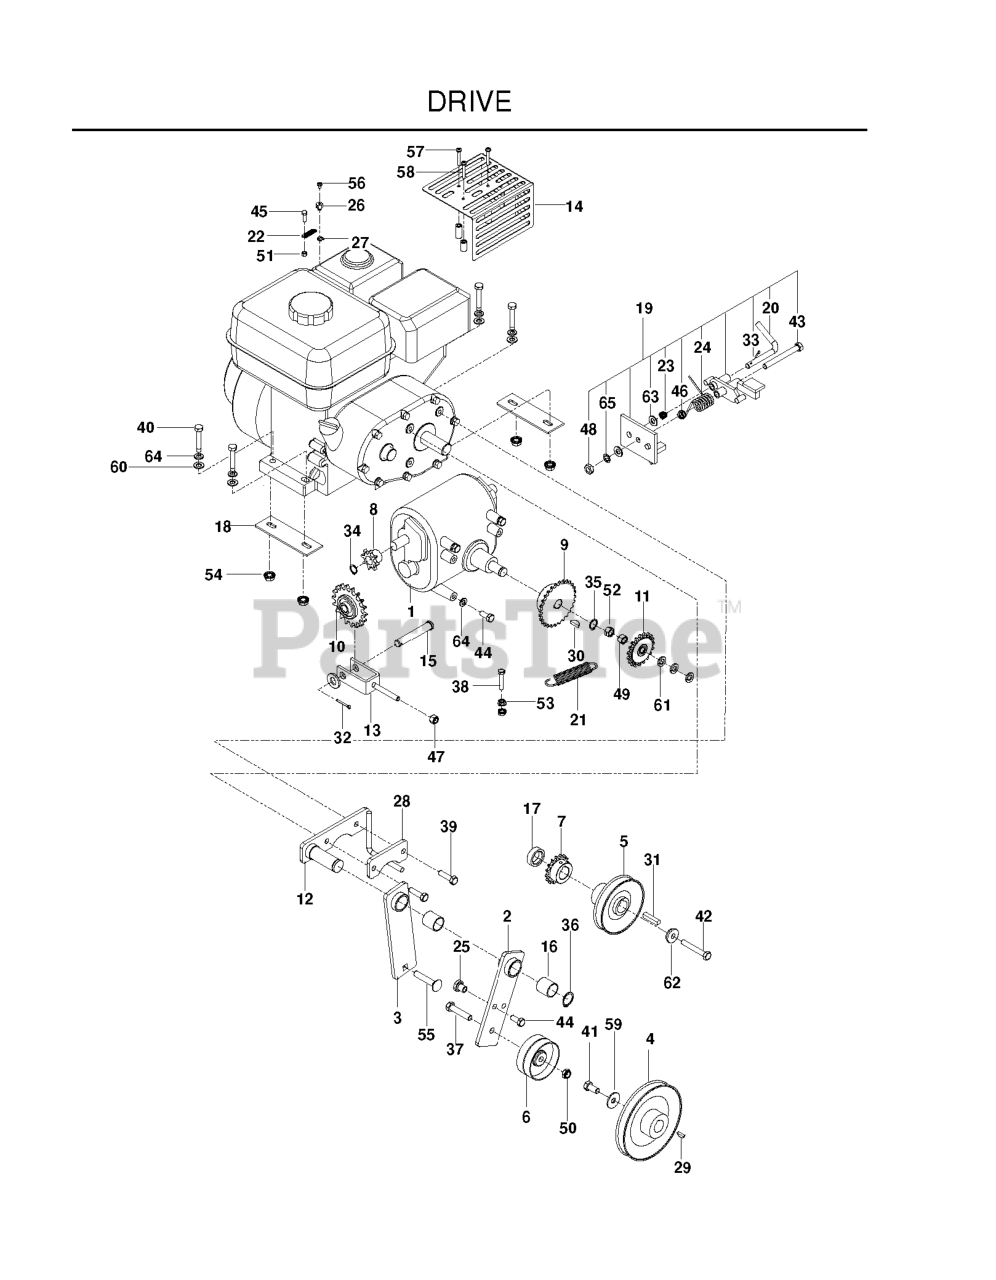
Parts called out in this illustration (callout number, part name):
1	TRANSMISSION-4 SP SOD CUTTER
2	BELT IDLER W/BUSHING
3	CHAIN IDLER W/BUSHING
4	PULLEY - 5.25 A
5	PULLEY - 3.75 A
6	PULLEY, IDLER 2 3/4 OD PAINTED
6	SPRING, 3 3/4", EXTENSION
7	SPROCKET, ENGINE
8	SPROCKET #40 CHAIN
9	SPROCKET, TRANSMISSION
10	SPROCKET, CHAIN TENSIONER
11	SPROCKET - IDLER 35 PITCH
12	IDLER PIVOT, BLACK
13	KIT TENSIONER ASSY/DRIVE CHAIN
14	SHIELD - HEAT (BLACK)
15	PIN CLEVIS 1/2 X 3 ZD
17	SPACER - PTO SHAFT
18	R/B 7203 PLATE, ENGINE BOLT
19	PARKING BRAKE ASSY, SOD CUTTER
20	HANDLE, BRAKE
21	SPRING AXLE AERATOR
22	SPRING, THROTTLE, HONDA ENGINE
23	KNOB SPRING KIT, DEPTH/STAB.
24	SPRING, TORSION, LIFT ARM
25	SPRING ANCHOR
26	CLAMP, THROTTLE CABLE
27	CLIP, THROTTLE HONDA
28	KEEPER - CHAIN, BLACK
29	KEY-WOODRUFF, #6
30	KEY, #9 WOODRUFF
31	KEY 7MM SQ X 33MM ENGINE
32	PIN COTTER 1/8 X 1 ZD
33	RP_COTTER PIN 1/8 X 3/4
34	RING RETAINING 9/16 EXT PLAIN
35	RETAINER RING
36	RETAINING RING, 7/8"
37	HCS 3/8-16 X 1 3/4 GR5
38	BOLT HEX 1/4 X 1-1/4
39	HCS M8-1.25 X 30MM
40	HCS 5/16C X 1 3/4
41	HCS 3/8F X 3/4
42	HCS M8-1.25 X 55MM GR8.8 ZD
43	HSC 1/2-13 X 4-1/2
44	HCS 5/16C X 3/4
45	HCS M5-0.8 X 16MM GR 8.8 ZD
46	NUT 1/2-13 HEX JM NYL
47	NUT 5/16 NYLOC
48	NUT 1/2-13 HEX HEAVY JAM ZD
49	NUT 3/8-16 NYLOC
50	NUT HEX 3/8-16 NYLON, THIN
51	NUT 5MM-.8 HEX ZD
52	NUT 3/8C CENTERBLOCK
53	NUT 1/4-20 HEX FLG LK ZD
54	5/16-18 NYLOC FLANGE NUT
55	RHSNB 3/8C X 2
56	SCREW METRIC SPECIAL X 1/4 ZN
57	SCR M5-0.8X40 PHIL PAN HD MACH
58	SCR M5-.08X35 PHIL PAN HD MACH
59	SPRING WASHER - .38
60	FLAT WASHER 5/16 SAE
61	SLW 3/8 STD
62	WASHER - STEPPED
63	WASHER 1/2" FLAT
64	WASHER.LOCK.HVY.HLCL.SPR.5/16
65	WASHER 1/2
